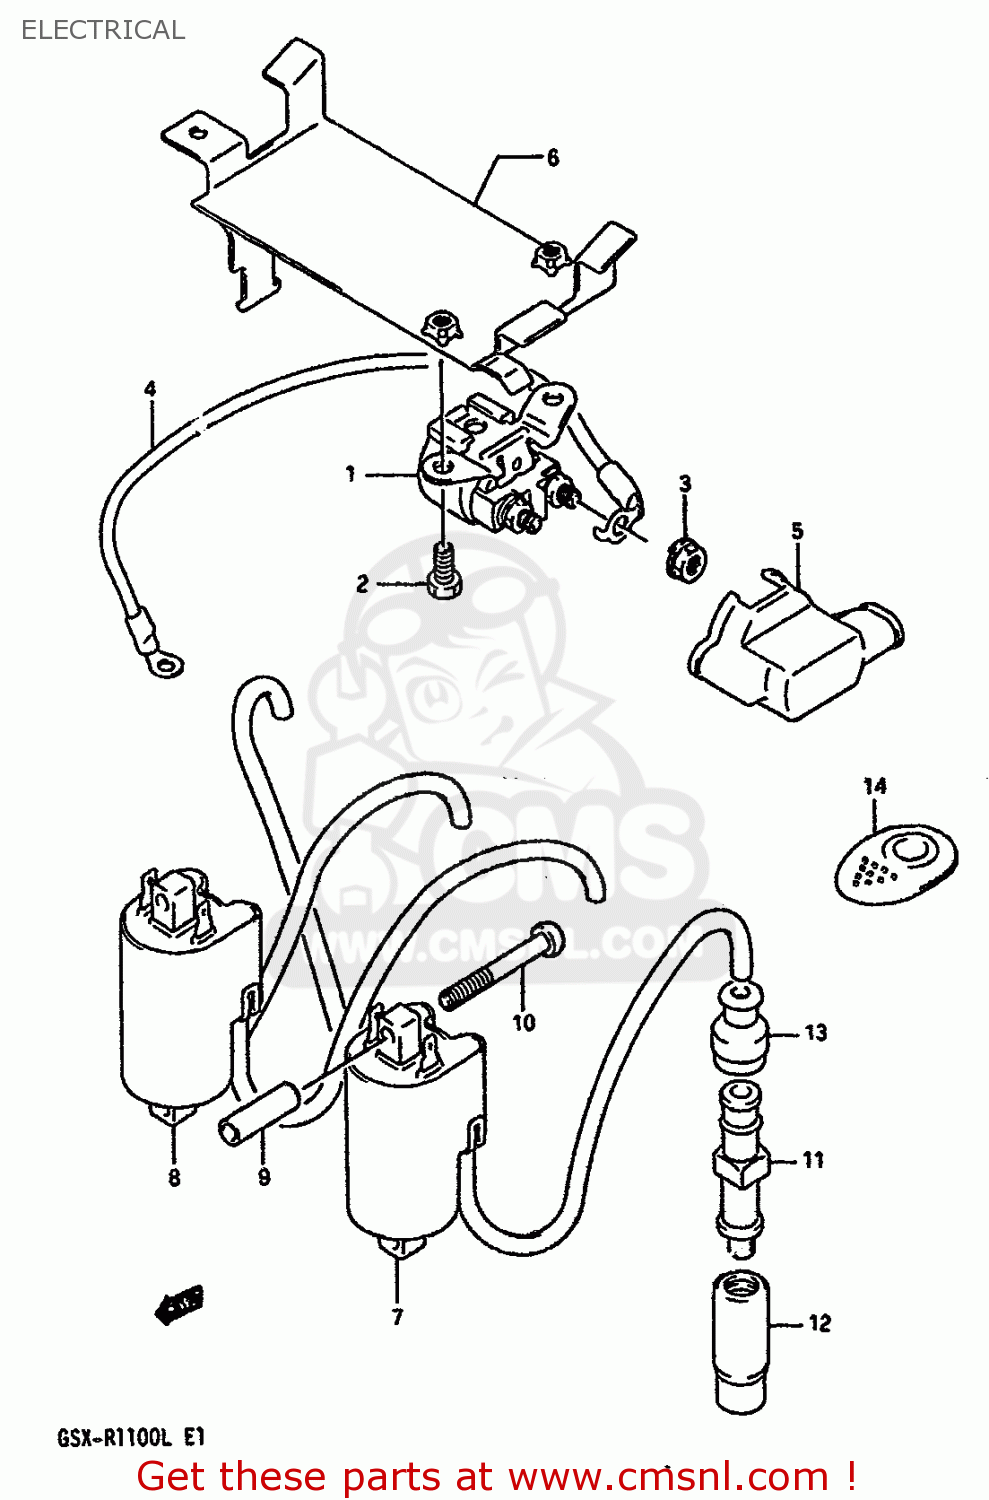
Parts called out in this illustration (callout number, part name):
1	RELAY ASSY,STARTING MOTOR
2	SCREW(6X8)
3	NUT
4	WIRE,STARTER MOTOR LEAD
5	COVER,RELAY ASSEMBLY
6	HOLDER COMP,ELECTRONIC PARTS
7	COIL ASSEMBLY,IGNITION
8	COIL ASSEMBLY,IGNITION
9	SPACER(6.4X10X32)
10	SCREW
11	CAP,SPARK PLUG
12	SEAL,SPARK PLUG
13	SEAL,HIGH TENSION CORD
14	COVER,SPARK PLUG CAP
